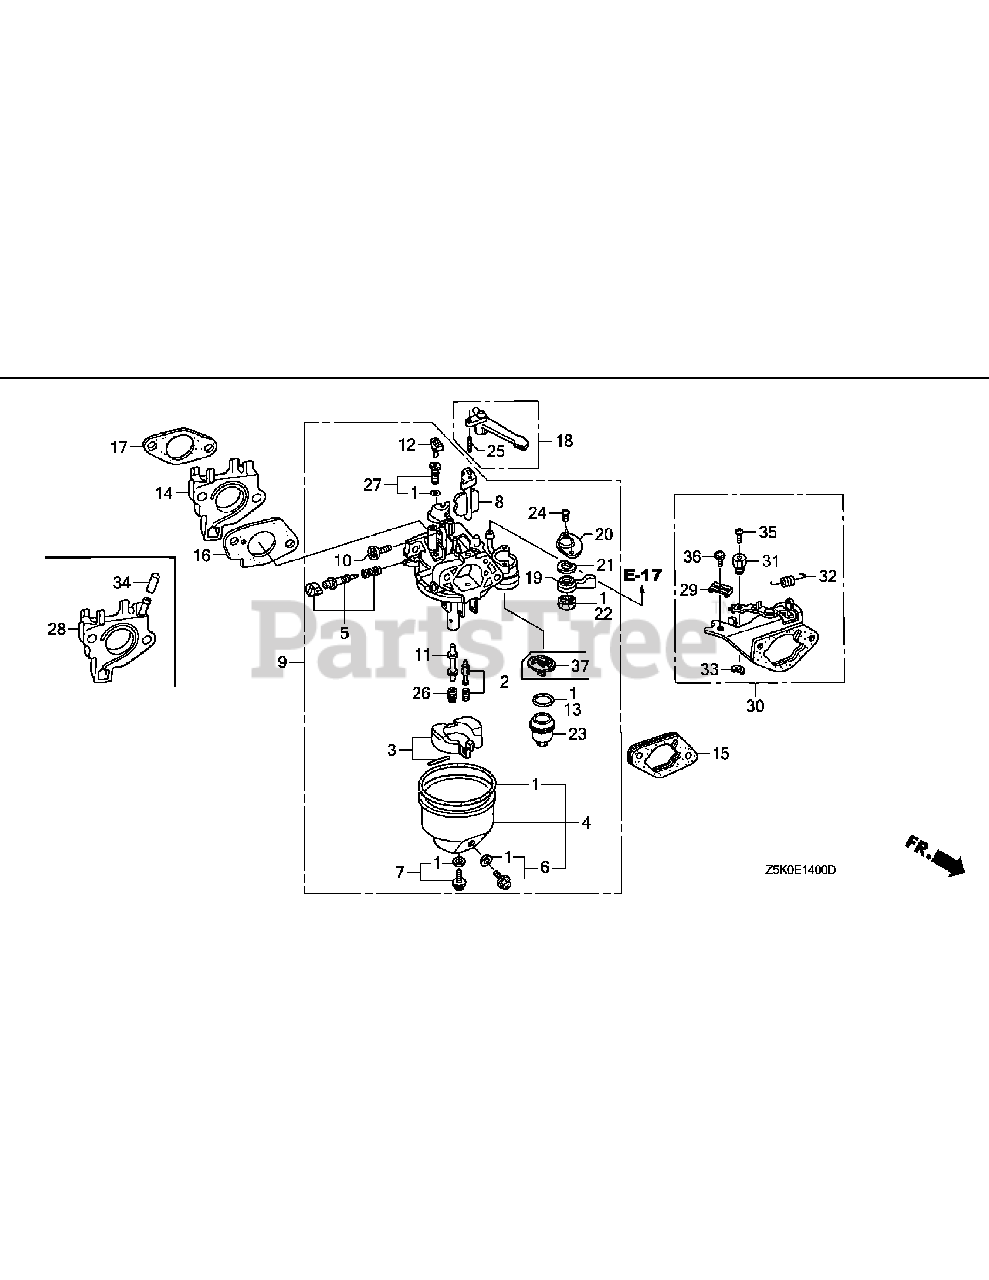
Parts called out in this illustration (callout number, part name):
1	Gasket Set
2	Valve Set, Float
4	Chamber Set, Float
5	Screw Set, Pilot
6	Screw Set, Drain
9	Carburetor Assy.(Be21J A)
10	Screw, Throttle Stop
11	Nozzle, Main
12	Collar, Setting
13	Packing, Fuel Strainer Cup
14	Insulator, Carburetor
15	Spacer Comp., Carburetor
16	Packing, Carburetor
17	Packing, Insulator
18	Lever Comp., Choke(Std.)
19	Lever, Cock
20	Plate, Lever Setting
21	Spring, Cock Lever
22	Packing, Fuel Cock
23	Cup, Fuel Strainer
24	Screw, Pan, 3X6
25	Pin, Spring, 2X12
26	Jet, Main, #82
26	Jet, Main, #85
26	Jet, Main, #88
27	Jet Set, Pilot, #38
28	Insulator, Carburetor
29	Holder, Cable
30	Stay Assy., Choke Control (Remote)
31	Holder, Wire
32	Spring, Return
33	Circlip, 5Mm
34	Cap, Sealing
35	Screw, Pan, 4X6
36	Screw-Washer, 5X16
37	Filter, Cup
